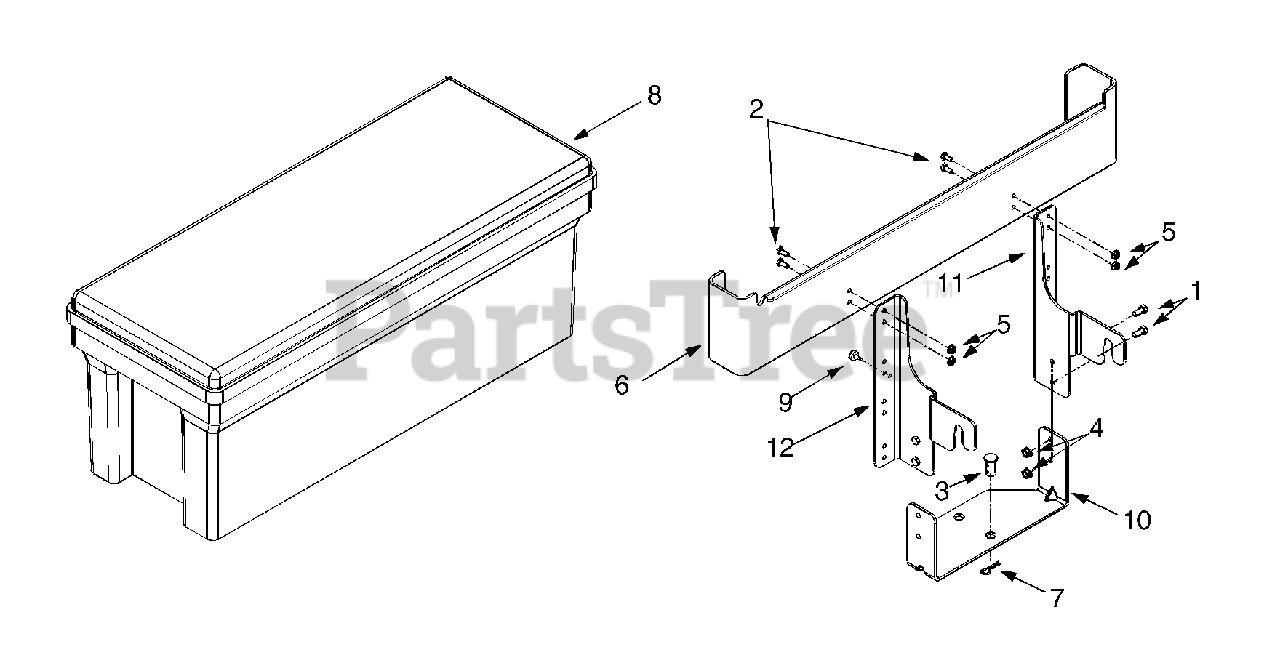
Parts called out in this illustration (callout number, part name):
1	Hex Cap Screw, 5/16-18 x .75
2	Hex Cap Screw, 1/4-20 x .62
3	Clevis Pin
4	Hex Flange Lock Nut, 5/16-18
5	Hex Flange Lock Nut, 1/4-20
8	Plastic Tool Box
9	Bumper, .62 Dia. x .3
